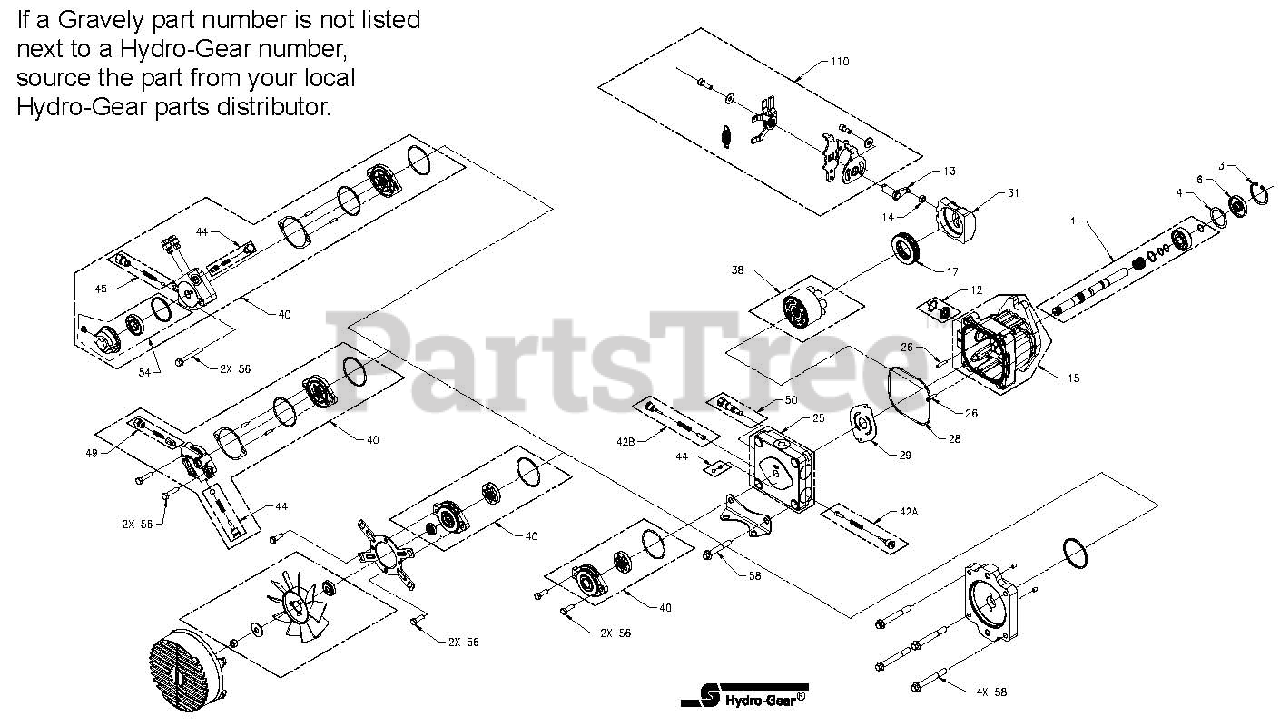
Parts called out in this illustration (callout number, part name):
1	Kit, Input Shaft
3	Ring, Retaining
4	Washer, 1.45 x 1.84 x .04
6	Lip Seal, 17 x 47 x 8
12	Kit, Trunnion Seal
13	Trunnion Arm, Taper Square
14	Slot Guide
15	Kit, Housing
17	Assembly, Thrust Ball Bearing
25	Kit, Encap
26	Pin
28	O-Ring
29	Valve Plate
31	Variable Swashplate
38	Kit, Cylinder Block
40	Kit, Charge Pump
42	Kit, Shock Valve
44	Kit, Charge Relief
45	Kit, Auxilary Relief Valve
49	Kit, Auxilary Bypass/Check Kit
50	Kit, Bypass Valve
54	Kit, Auxilary Filter Kit
56	Screw, 5/16-18 x 1
58	Kit, HSG Bolt
110	Kit, Return
NS	Kit, Overhaul Seal Kit
